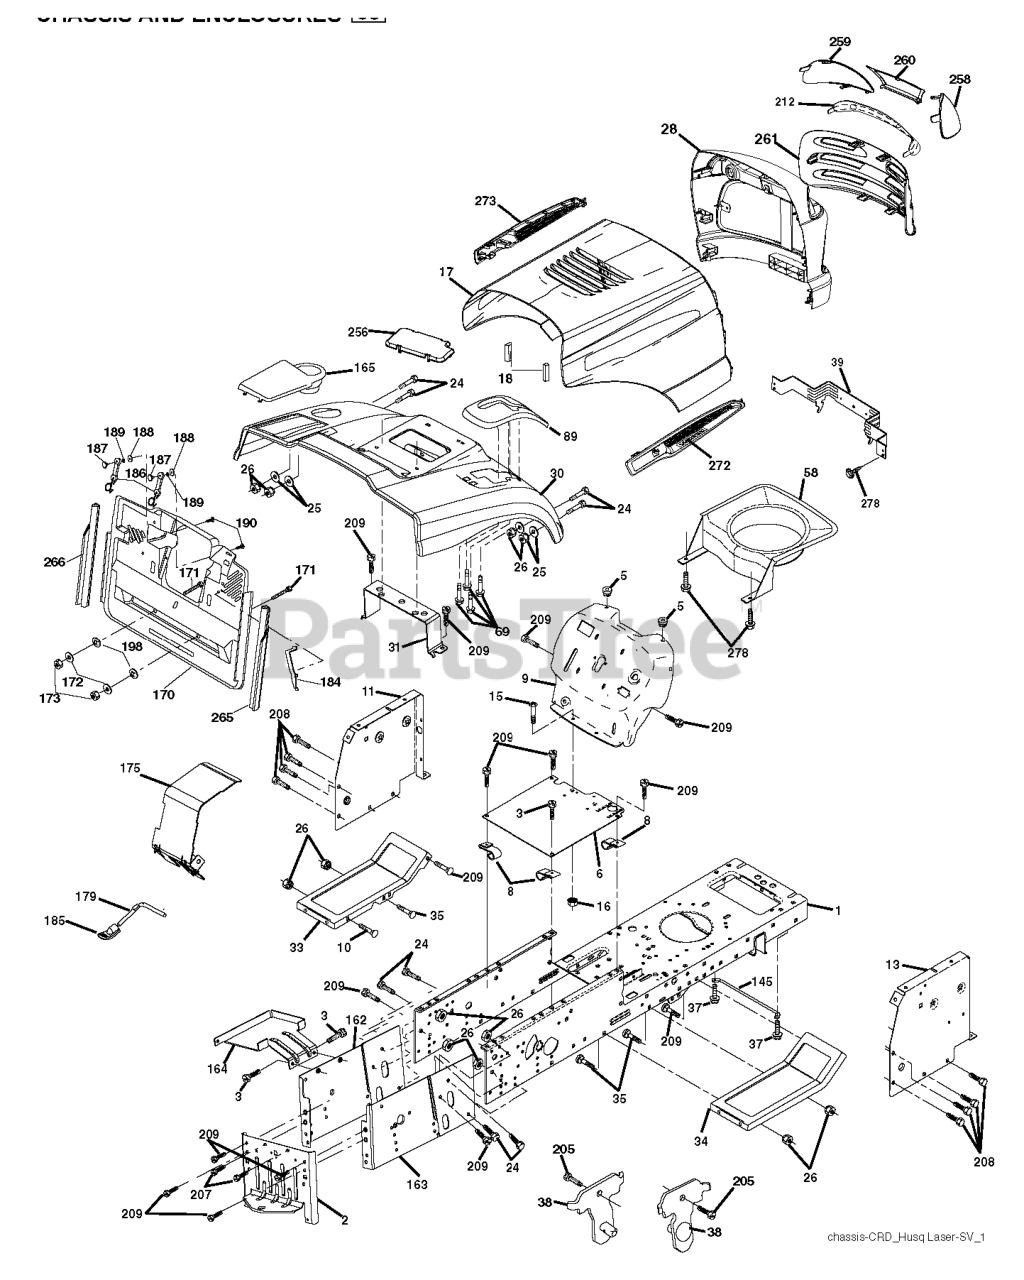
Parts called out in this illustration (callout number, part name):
2	DRAWBAR
3	SCREW 3/8-16X3/4
5	BUMPER.RUBBER.HOOD
6	PLATE
8	CLIP,INSULATOR
9	DASH.SLK.LT.PL.CC.NA.NHM.CE
10	BOLT D
11	PANEL.DASH.LH.LTX
13	PANEL ASM, DASH RH
15	Screw, Machine, Truss Head 5/16-18 UNC x 3/4
16	NUT
17	VENT.HOOD.LASER.III
18	BUMPER.HOOD.LARGE.1.75"
25	WASHER
26	NUT
30	CONSOLE.CRD.AUTO.GRY
31	BRACKET SUPPORT FENDER
33	FOOTREST.PNT.LH.BLACK
34	FOOTREST, RH
37	Screw 5/16-18 x 1/2 Hex, Self Tapping 5/16-18 x 1/2
38	BRACKET ASM PIVOT MOWER REAR
39	BRACKET PIVOT
69	SCREW.HI-LO.CONSOLE
89	CONSOLE.CRD.6SP.BLACK
145	ROD.PIVOT.HOOD
162	BRACKET
163	BRACKET EXTEN CHASSIS RH CRD
165	COVER.BATTERY.CRD.BLACK
172	WASHER
175	DOOR TRAP
179	ROD PIVOT FBI
184	BRACKET.ACTUATOR.BAGGER.SRD
186	LATCH ASSY
187	WELDNUT
189	LOCKWASHER #10
190	SCREW
207	SCREW, 5/16-18 X 1/2
208	SCREW 3/8-16X1/2
209	SCREW, 3/8-16X3/4
212	INSERT.LENS.REFLECTIVE
256	COVER FENDER CRD
258	LENS LH
259	LENS LH
260	COVER.LENS.HUSQ.LASER
265	SEALING
266	SEALING
272	VENT.HOOD.LASER.
273	VENT.HOOD.LASER.
278	SCREW.#10 X 0.750.BOS
